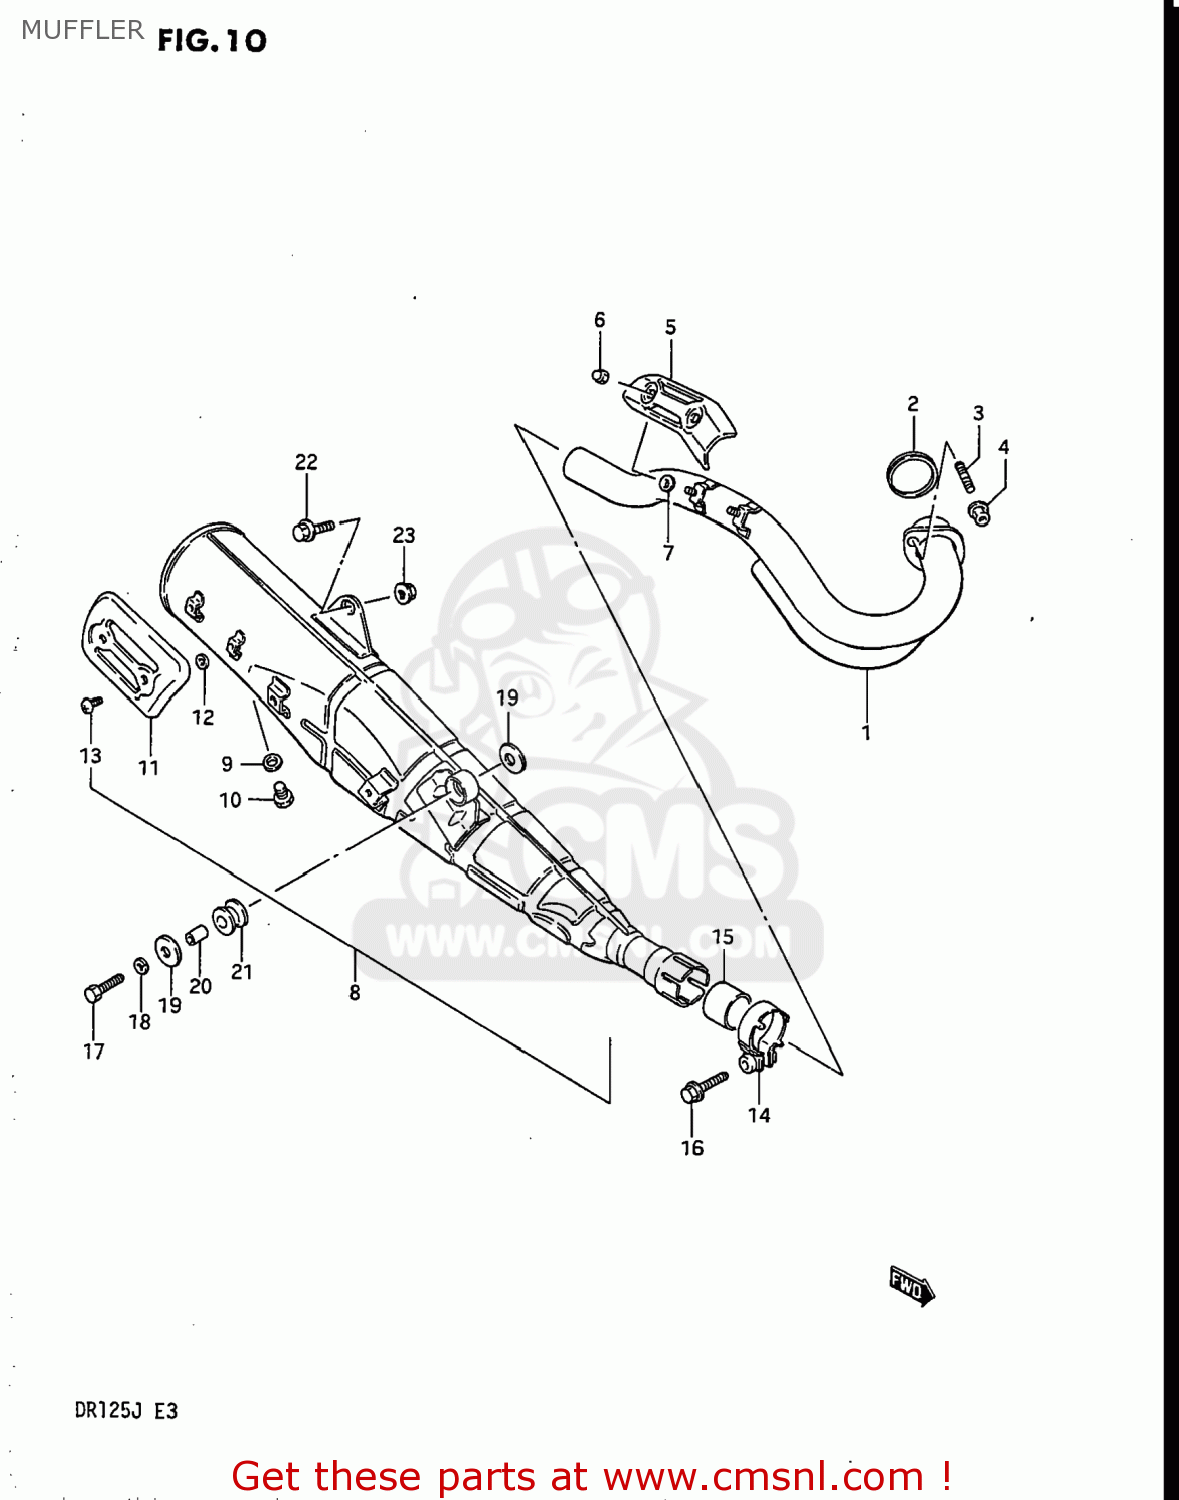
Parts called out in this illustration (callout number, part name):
1	PIPE,EXHAUST
2	GASKET,EXHAUST PIPE (NAS)
3	BOLT,STUD
4	NUT
5	COVER,EXHAUST PIPE
6	NUT (6MM)
7	GASKET (NAS)
8	MUFFLER ASSEMBLY
9	GASKET(12.1X16.2X3.7) (NAS)
10	PLUG(12X9)
11	COVER,MUFFLER
12	GASKET (NAS)
13	SCREW
14	CLAMP,MUFFLER CONNECTOR
15	CONNECTOR,MUFFLER
16	BOLT
17	BOLT
18	WASHER,LOCK,8.
19	WASHER (8.5X20X1.6)
20	SPACER (8.6X12X17.5)
21	CUSHION
22	BOLT(8X25)
23	NUT
